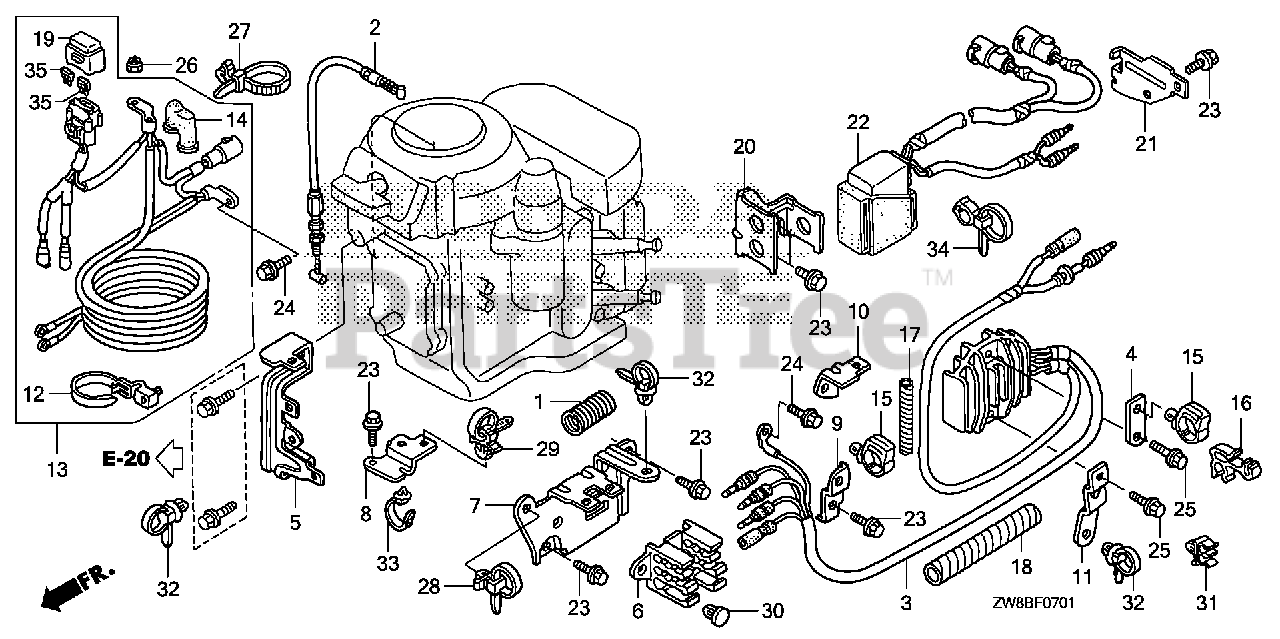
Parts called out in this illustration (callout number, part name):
2	CABLE, NEUTRAL STARTING
3	RECTIFIER ASSY., REGULATOR
4	BRACKET, CLIP F
5	BRACKET, CONNECTOR (A)
6	BRACKET, CONNECTOR (B)
7	BRACKET, CONNECTOR
8	BRACKET, STARTER CABLE
9	BRACKET, CLIP B
10	BRACKET, FUSE CASE
11	BRACKET, E-CLIP
12	BAND, WIRE
13	CABLE ASSY., STARTER (R/C PT)
14	COVER, MAGNETIC SWITCH TERMINAL
15	CLAMP, ENGINE SUB-WIRE
16	CLAMP, DISTRIBUTOR WIRE
17	TUBE, SPIRAL C
18	TUBE, SPIRAL A
19	COVER ASSY., FUSE (20A)
20	BRACKET, POWER TILT RELAY
21	BRACKET, CONNECTOR A
22	RELAY ASSY., POWER TILT
23	BOLT, FLANGE (6X14) (CT200)
24	BOLT, FLANGE (6X12)
25	BOLT, FLANGE (6X26) (CT200)
26	NUT, LOCK (6MM)
27	BAND, WIRE (95MM)
28	STRAP, CABLE (118MM) *NH1L* (Honda Code 1170653). (BLACK)
29	STRAP, CABLE (105MM) *NH1* (Honda Code 1685536). (BLACK)
30	CLIP, ANCHOR
31	CLIP, FUEL TUBE
32	CLIP, HARNESS BAND (151.5MM) (NATURAL)
33	BAND, WIRE HARNESS (123.5MM) (BLUE)
34	CLIP, TUBE (135MM) (BLACK)
35	FUSE, BLADE (20A)
